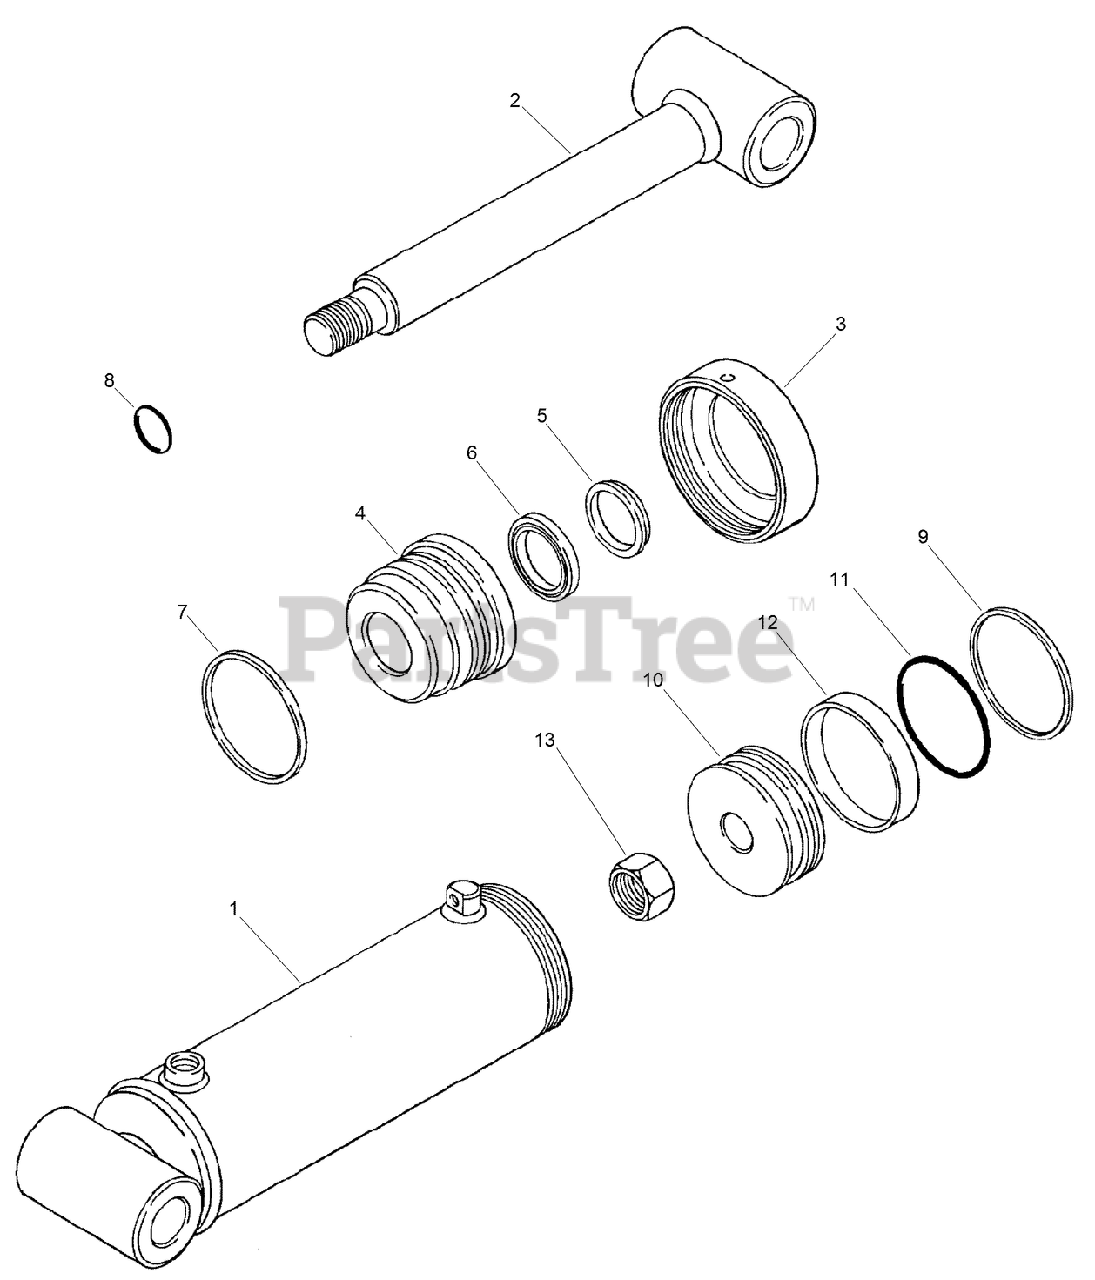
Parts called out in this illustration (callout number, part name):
1	TUBE - Cylinder
2	ROD - Piston
4	GLAND - Cylinder
5	WIPER - Piston Rod
6	SEAL - Piston Rod
7	O-RING - 3-1/4 ID x 1/8
8	O-RING - 7/8 ID x 1/16
10	PISTON - Cylinder
11	O-RING - 3 ID x 3/32
12	RING - Wear
13	NUT - Lock
